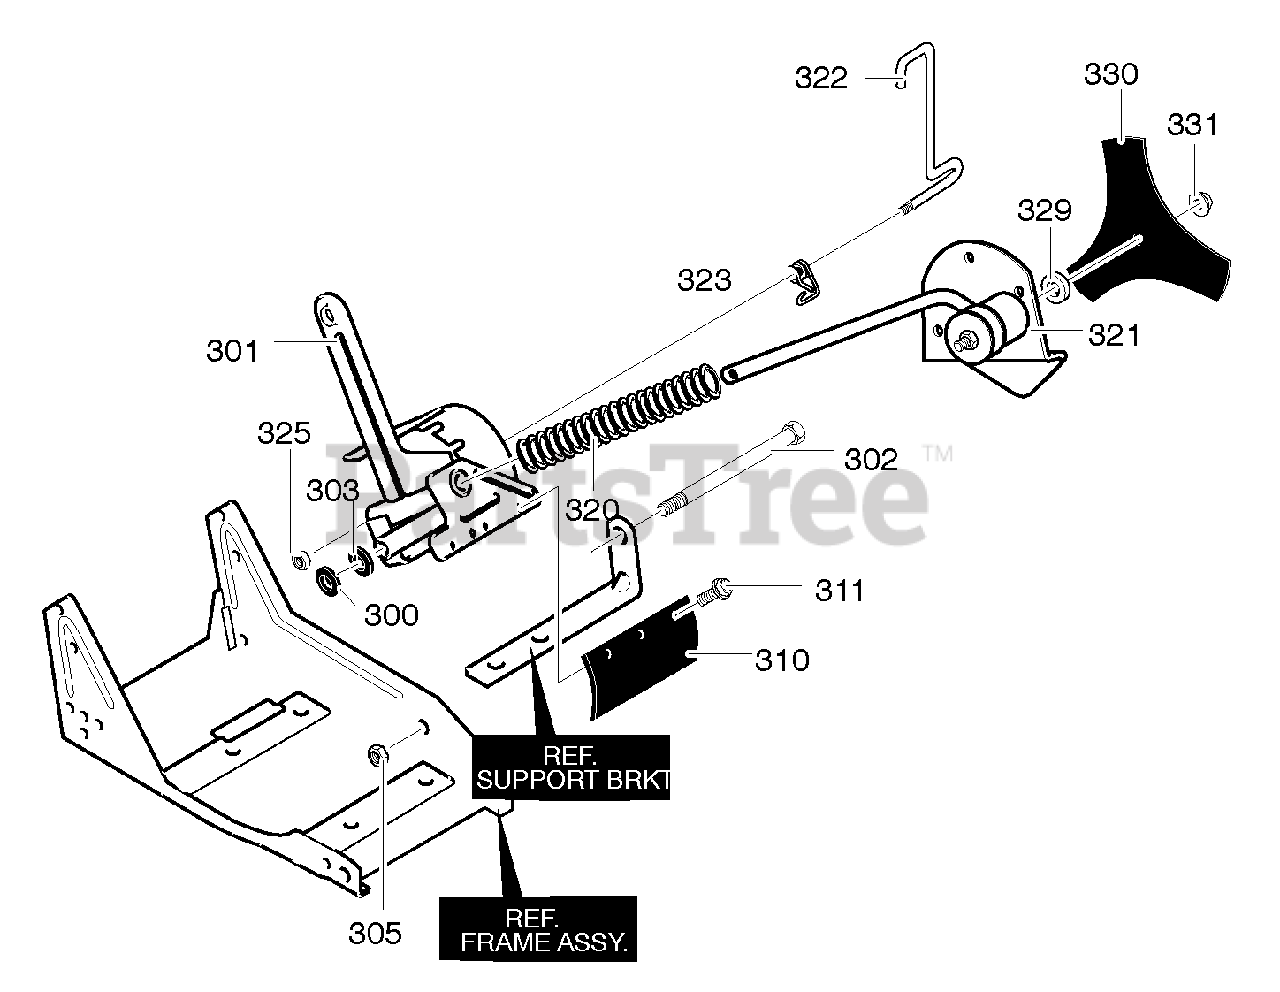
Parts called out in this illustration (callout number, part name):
300	Flatwasher
301	Quill Support
302	Bolt, 3/8-16
303	Flatwasher
305	Nut, 3/8-16
310	Rubber Deflector
311	Screw, 10-16x1.50
321	Quill Assembly
322	Lever, Index
323	Spring, Torsion
325	Nut, 5/16-18
329	Flatwasher
330	Blade, Edger
331	Nut, 1/2-20
